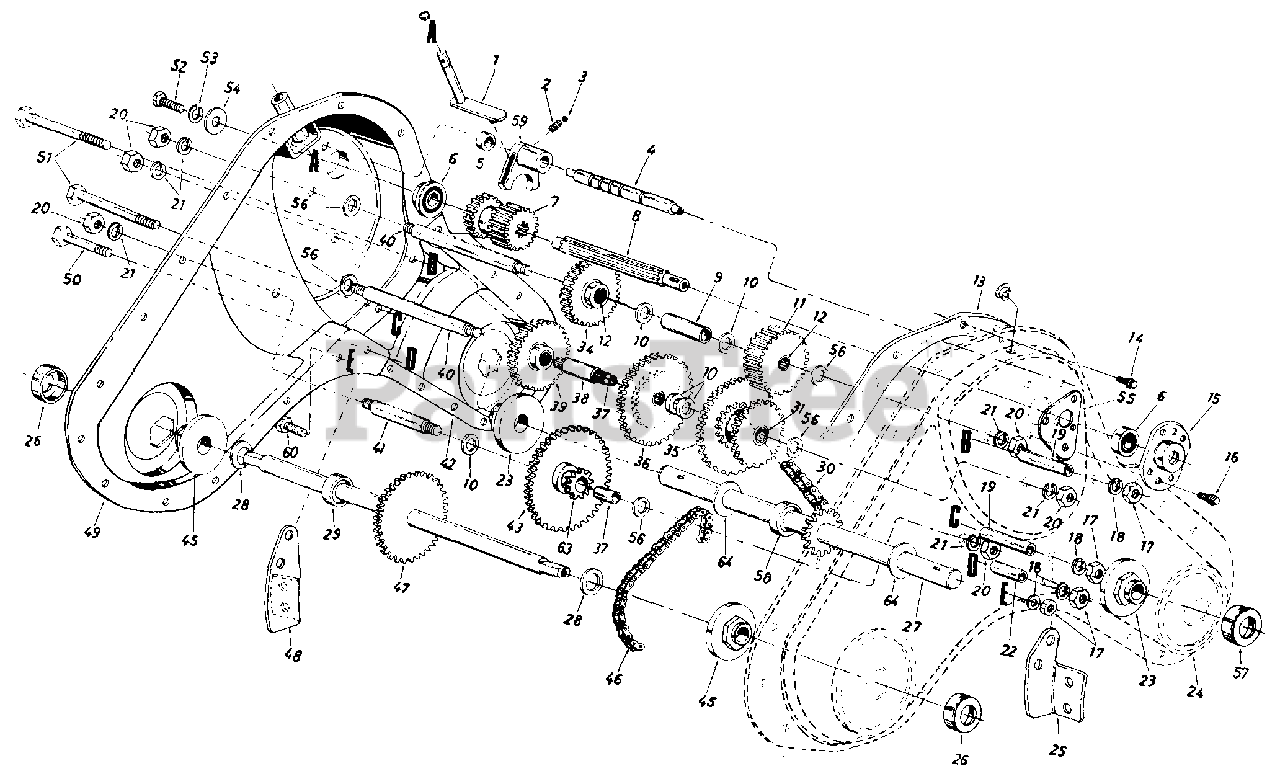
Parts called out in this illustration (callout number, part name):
1	Shifting Bracket Ass'y.
2	Compression Spring .50" Lg.
3	Ball Detent .250" Dia.
4	Detent Shaft 1/2" Dia.
5	Spacer .505" I.D. x .88" O.D.
6	Ball Brg. .62" I.D. x 1.38"
7	Spur Gear 16T (Input)
8	Input Spline Shaft 7/8"
9	Spacer .657" I.D. x 2.85" Lg.
10	Fl-Wash. .640" I.D. x 1.24"
11	Spur Gear 30T 7/8" I.D.
12	Needle Bearing 5/8" I.D.
13	Gasket-Trans. Hsg.
14	Hex S-Tap Scr. 1/4-20 x .5"
15	1-3/8" Dia. Bearing Housing
16	Hex TT-Tap Scr. 1/4-20 x .75"
17	Hex Nut 5/16-18 Thd.
18	L-Wash. 5/16" I.D.
19	Spacer 1.56" Lg.
20	Hex Nut 7/16-20 Thd.
21	Bell-Wash. .45" I.D. x 1.0"
22	Spacer 1.015" Lg.
23	Tine Shaft Brg. 1.002 x 2.50
24	Trans. Housing Ass'y.-L.H.
27	Tine Shaft Ass'y. 1" O.D.
28	Fl-Wash. .76" I.D. x 1.5" O.D.
29	Spacer .75" I.D. x .50" Lg.
30	Chain #50 5/8 Pitch x 52 Links-Endless
31	Needle Bearing 5/8" 1 .D.
34	Spur Gear 30T 12/16" I.D.
35	30/44T Gear Ass'y. Comp.
36	Spur Gear 44T
37	Sleeve Bearing
38	Gear Hub 3/4" I.D. x 3" Lg.
39	Spur Gear 30T 1.0" I.D. x 1/2" W
40	Jack Shaft 5/8" Dia. x 5"
41	Jack Shaft 5/8" Dia. x 2.38"
45	Wheel Brg. .752" x 2.5"
46	#420 Chain 1/2 Pitch x 50 Links-Endless
47	Wheel Shaft Ass'y. 15.6"
51	Hex Bolt 5/16-18 x 2.5"
52	Hex Bolt 1/4-20 x .62" Lg.
53	L-Wash. 3/8" I.D.
54	Fl-Wash. 1/4" I.D. x .93" O.D.
55	Gear Positioner Bracket
56	Fl-Wash. 7/16" I.D. x 1-3/8"
57	Dust Cover Ass'y. 1" Shaft
58	Spacer 1" I.D. x 2" O.D.
59	Shifting Fork
60	Hex Bolt 5/16-18 x .75" Lg.
63	10T Sprocket Ass'y.
64	Thrust Wash. 1.03" I.D. x 1.62" O.D.
